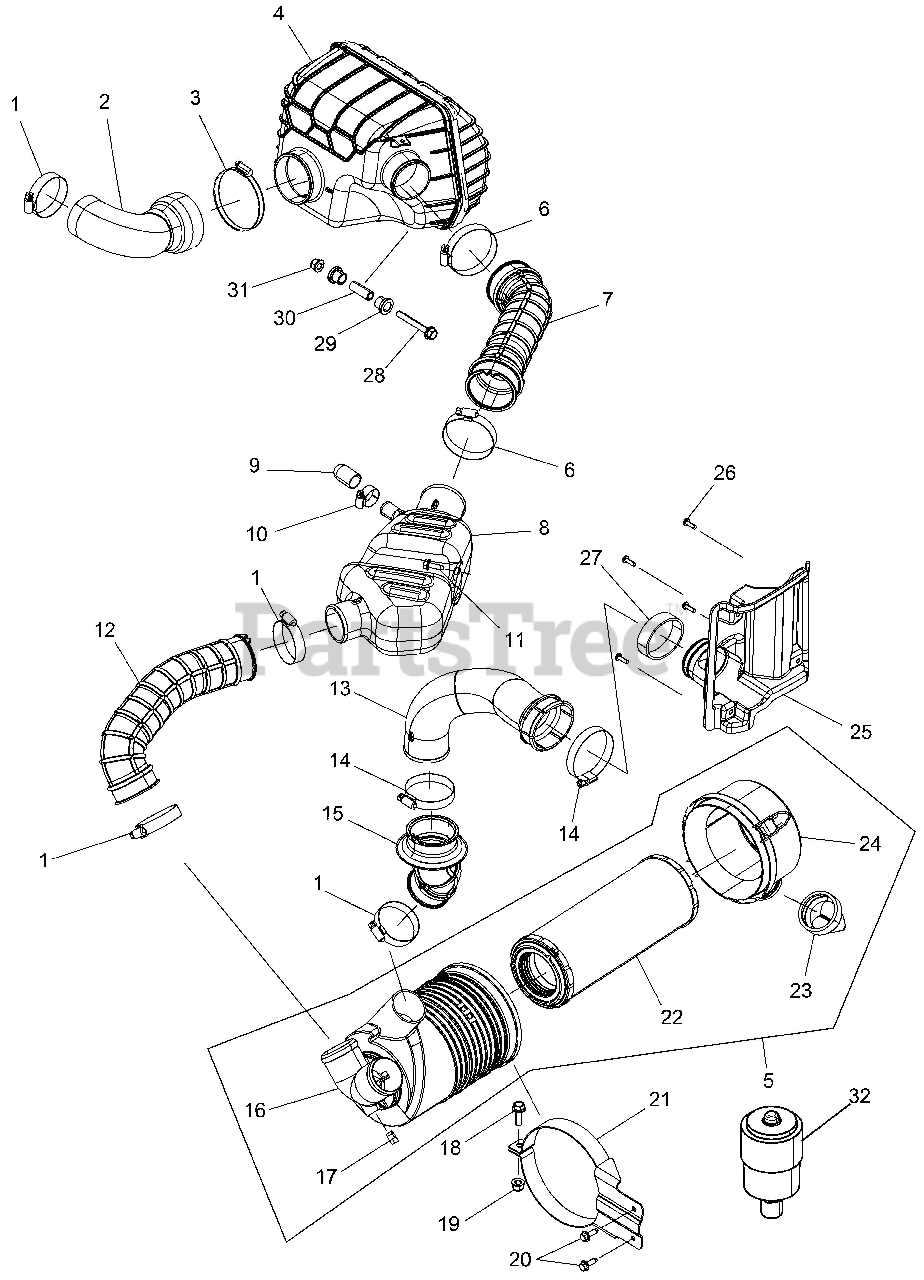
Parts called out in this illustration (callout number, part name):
1	CLAMP, HOSE, S.S.(10)
2	HOSE-INTAKE,ENG,DSL
3	CLAMP-BAND,NARROW 70-90MM
4	WELD-INTAKE,PLENUM
5	ASM., AIR INTAKE
6	CLAMP-HOSE, 2.75"-SS
7	HOSE-INTAKE,ENG
8	DUCT-INTAKE,ENG
9	CAP-RUBBER,.75 ID X 1.00
10	CLAMP,HOSE
11	SCR-M6X1.0X20,HXHD,FLG,TDFM,BL
12	HOSE-AIR BOX,SPLY
13	DUCT-INTAKE,AIR
14	CLAMP, HOSE
15	HOSE-INTAKE,AIR BOX,SPLY
16	ASM., AIRBOX, MAIN
17	PLUG-AIRBOX
18	BOLT-M8X1.25X25,HXFLG-OLIVE D
19	NUT-M8X1.25,FLG,NYLOC-OLIVE D
20	SCR-M6X1.0X20,HXHD,FLG,TDFM,BL
21	WELD-AIRBOX,MOUNT
23	VALVE-AIRBOX
24	ASM-LID,AIRBOX
25	INTAKE-FENDER,REAR,BLK
26	SCR-10X5/8-HI/LO,PN-T25,TRX-M
27	HOSE-INTAKE,BOOT
28	SCR-HXFL-M8X1.25X60 8.8 ZOD
29	BUSHING-MOUNT
30	SHAFT-COMPRESSION LMTR,34.4MM
31	NUT-M8X1.25,FLG,NYLOC-OLIVE D
32	KIT, FILTER, INDICATOR
